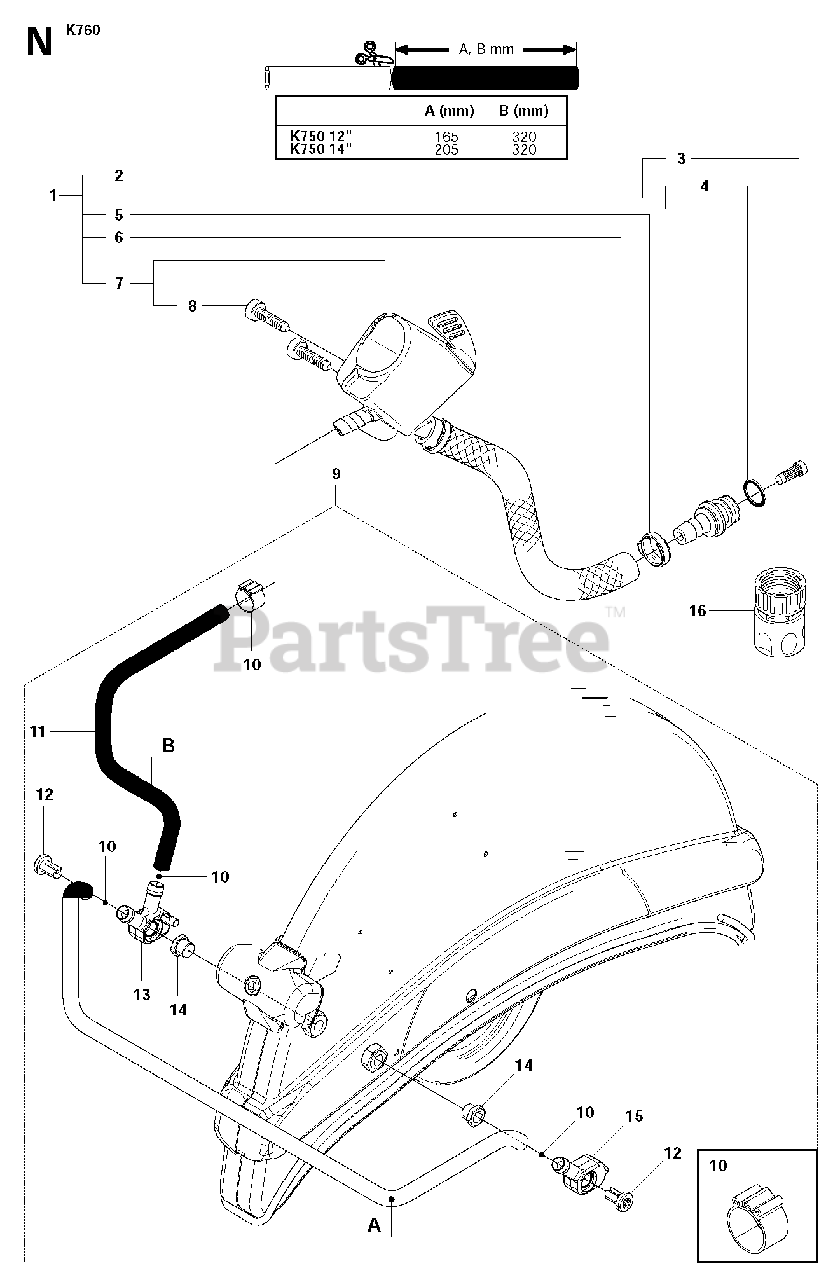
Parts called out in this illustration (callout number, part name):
1	HOSE KITIncl. 2, 5 - 7
2	NIPPLEIncl. 3, 4
5	HOSE CLAMP
7	VALVE ASSYIncl. 8
8	SCREW ITXSCT
9	HOSE KITIncl. 10 - 15
11	HOSE620 mm
12	SCREW ITXSCM
16	COUPLERUSA, Canada
